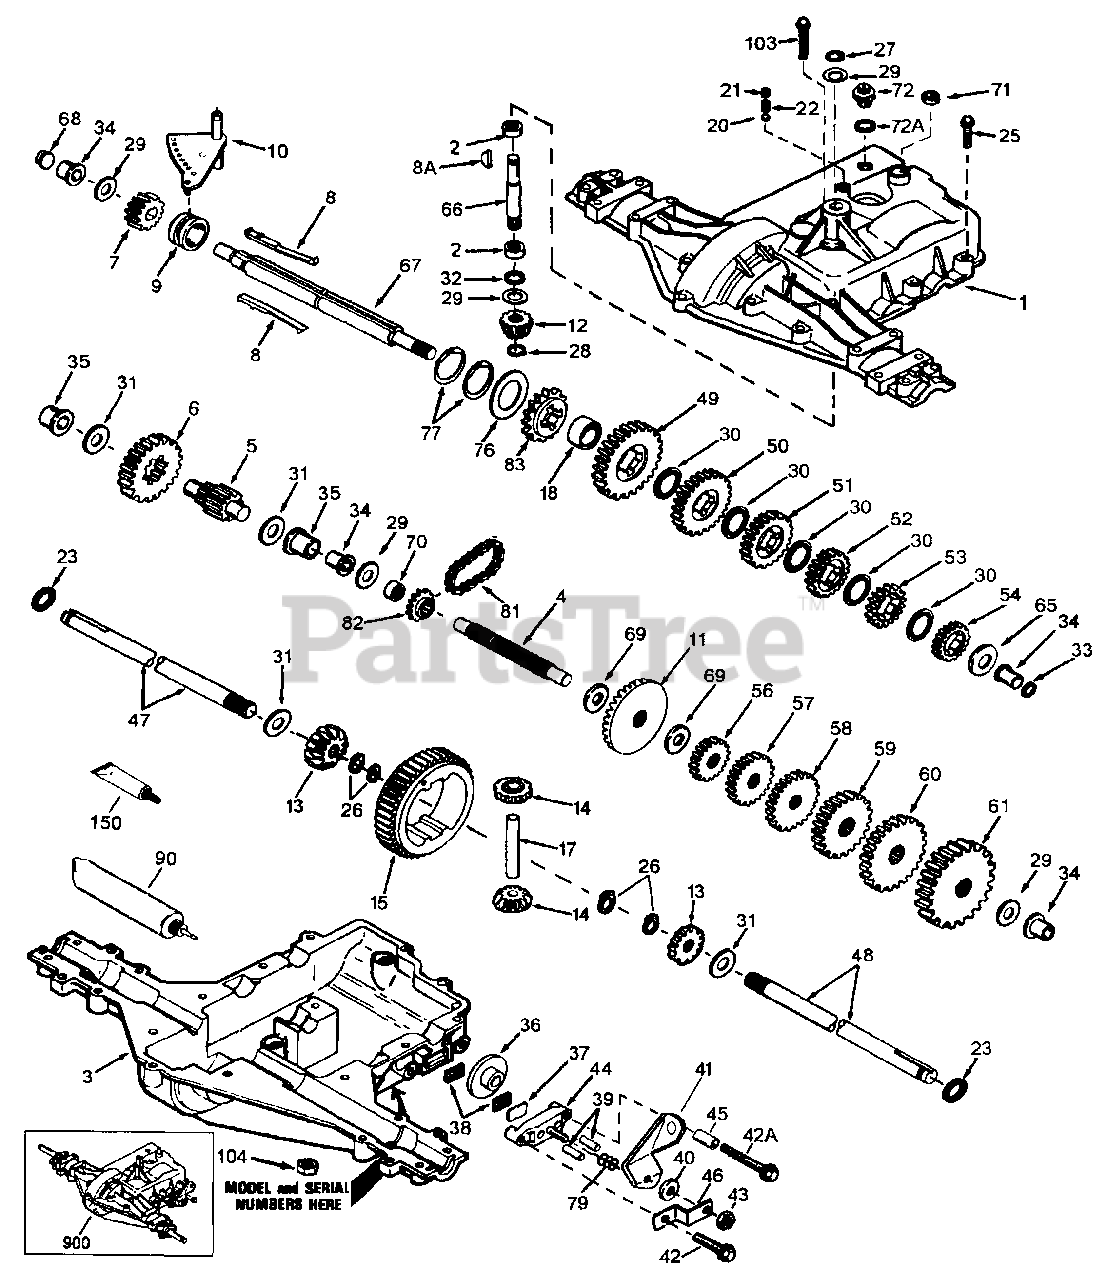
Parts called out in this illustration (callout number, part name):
1	Cover, Transaxle
2	Bearing, Needle
3	Case, Transaxle
4	Shaft, Counter
5	Shaft and Pinion Assembly, Output
6	Gear, Output
7	Gear, Spur, 15 Teeth
8	Key, Shift
8A	Key, Woodruff
9	Collar, Shifter
10	Rod and Fork Assembly, Shift
11	Gear, Bevel, 42 Teeth
12	Bevel Pinion, Input
13	Gear, Bevel
14	Gear, Bevel Pinion
15	Gear, Ring
17	Pin, Drive
18	Spacer, Neutral
20	Ball, Steel 5/16" diameter
21	Set Screw 3/8-16 x 3/8
23	Ring, Seal
25	Screw, Flanged Hex Head, Thread Forming 1/4-20 x 1-1/4
26	Ring, Retainer (4 Required, Package of 2)
27	Ring, Retainer
28	Ring, Retainer
29	Washer, Thrust
30	Washer, Thrust
32	"O" Ring
33	Seal, Square Cut
34	Bushing, Flanged
35	Bushing, Flanged
36	Disk, Brake
37	Plate, Brake Pad
38	Pad, Brake
39	Pin, Dowel
40	Washer, Flat
41	Lever, Brake
42	Screw, Flanged Hex Head, Thread Forming 1/4-20 x 1-1/4
42A	Screw 1/4-20 x 2-1/4
43	Locknut 5/16-24
44	Holder, Brake Pad
46	Bracket, Brake Lever
47	Axle 11-5/16" long
48	Axle 16-1/2" long
49	Gear, Spur, 37 Teeth, Steel (1 )
50	Gear, Spur, 35 Teeth (2")
51	Gear, Spur, 30 Teeth (3-)
52	Gear, Spur, 25 Teeth (4-)
53	Gear, Spur, 22 Teeth (5-)
54	Gear, Spur, 19 Teeth, Steel (6 )
56	Gear, Spur, 12 Teeth (1 )
57	Gear, Spur, 15 Teeth (2")
58	Gear, Spur, 20 Teeth (3-)
59	Gear, Spur, 25 Teeth (4 )
60	Gear, Spur, 28 Teeth (5-)
61	Gear, Spur, 31 Teeth (6 )
65	Washer, Thrust
66	Shaft, Input
67	Shaft, Brake, 4 Keyed
69	Washer, Thrust
71	Seal, Square Cut
72	Plug, Threaded 9/16-18
72A	"O" Ring
76	Washer, Thrust
77	Ring, Retaining, Inverted (Package of 2)
79	Spring, Brake
81	Chain, Roller (Number 41 Chain, 24 Links)
82	Sprocket, 9 Teeth (Reverse)
83	Sprocket, 18 Teeth (Reverse)
90	Grease, Bentonite, 32 Ounce Bottle
103	Screw 1/4-20 x 2
104	Locknut 1/4-20
150	Gasket Eliminator (Loctite #515)
900	Replacement Transaxle
